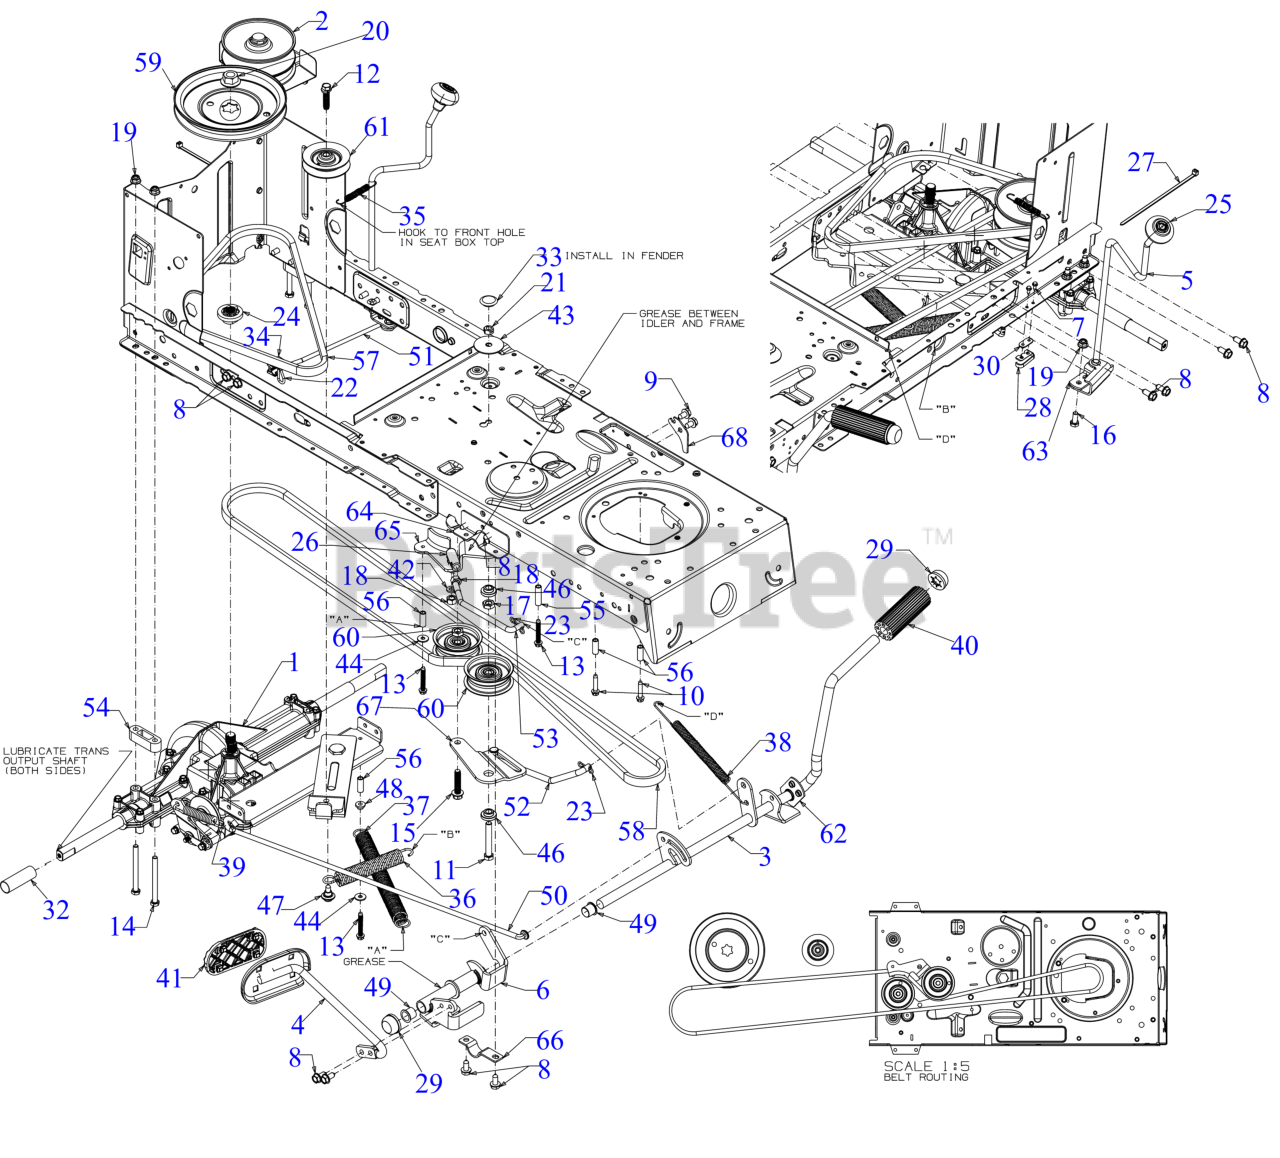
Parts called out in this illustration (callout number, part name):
1	SINGLE SPEED TRANSAXLE ASSEMBLY
2	VARIABLE SPEED PULLEY ASSEMBLY 4.75 OD
3	PEDAL ASSEMBLY
5	SHIFT LEVER ASSEMBLY
6	BRACKET ASSEMBLY
7	HEX SCREW WASHER HD #8-18 x 0.500
8	SCREW 5/16-18 x .750
9	SCREW 5/16-18 x .625
10	SCREW 1/4-20 x 1.25
11	HEX SCREW-3/8-16X2.5 GR5
12	SCREW 3/8-16 x 1.500
13	SCREW 1/4-20 x 1.750
14	SCREW 5/16-18X3.5 GR5
15	SCREW 3/8-16 x 1.75
16	SCREW 5/16-18 x .75 GR5
17	JAM NUT 7/16-20
18	HEX NUT 3/8-24
19	FLANGE LOCK NUT 5/16-18
20	FLANGE NUT W/HUB
21	LOCK NUT 3/8-16
22	COTTER PIN
23	BOW TIE COTTER PIN 1/4-5/16
24	PULLEY HUB
25	SHIFT KNOB
26	BALL JOINT
26	BALL JOINTS
27	7" CABLE TIE
28	SAFETY SPRING SWITCH
30	INSULATOR NUT PLATE
33	DECK HOLE PLUG
34	SHIFT ROD BEARING
35	EXTENSION SPRING .38 OD x 3.25 LG
36	EXTENSION SPRING .97 x 6.18
37	EXTENSION SPRING 1.00 x 11.125 x .095
38	EXTENSION SPRING .562 OD x 10.5
39	EXTENSION SPRING
40	BRAKE PEDAL PAD
42	LOCK WASHER 3/8
43	HUB CAP WASHER .406 x 1.92 x .060
44	FLAT WASHER
46	SHOULDER SPACER 1.00 x .38 x .38
47	SHOULDER SCREW .43X.29X5/16-18 TT
48	SHOULDER SPACER
49	NYLINER BEARING
52	TRANSMISSION FOOT PEDAL ROD
53	IDLER ADJUSTMENT ROD
54	TRANSAXLE SPACER
55	SPACER:.260 x .372 x 1.420
57	V-BELT 5L x 40.75
57	Genuine Factory Parts TRANSMISSION BELT
58	V-BELT 5L-90.93
58	Genuine Factory Parts TRANSMISSION BELT
59	V-PULLEY W/HUB 7.25 DIA
60	FLAT IDLER PULLEY 2.75 OD
61	V-IDLER PULLEY A x 3.06 OD
63	SHIFT ADJUSTMENT BRACKET
64	PEDAL FRAME BRACKET (RH)
65	DOULE IDLER BRACKET
66	SUPPORT BRACKET
67	IDLER BRACKET
68	PEDAL STOP PLATE
